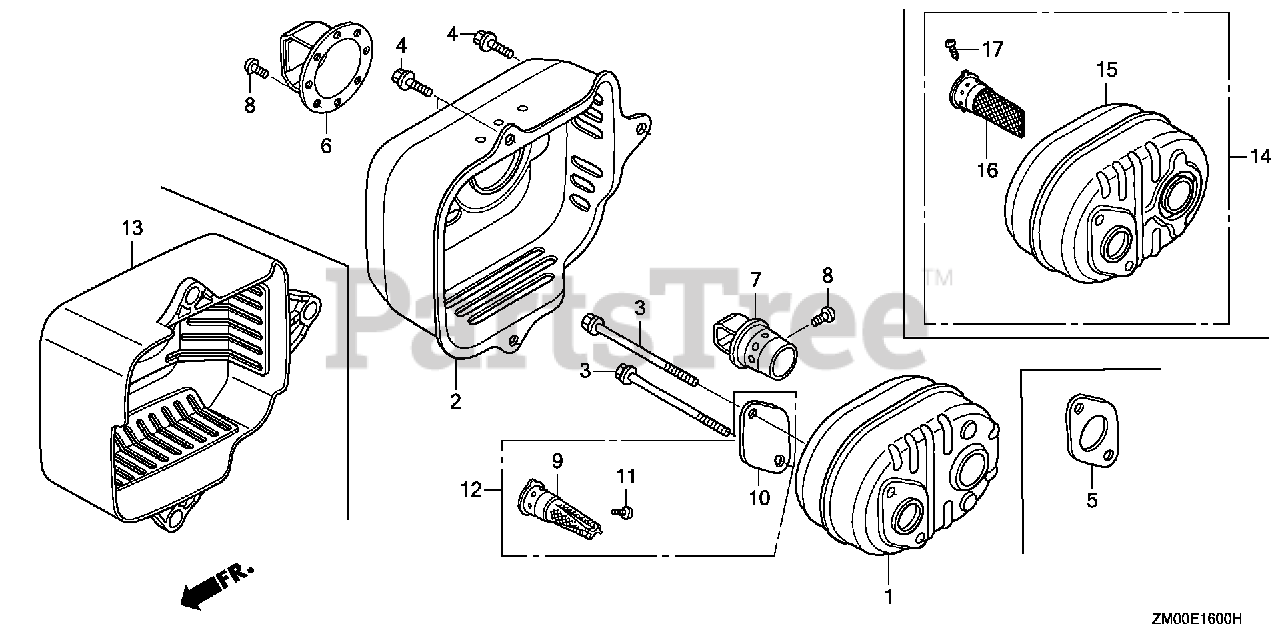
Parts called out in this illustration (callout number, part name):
2	PROTECTOR, MUFFLER
3	BOLT, FLANGE (6X79) (CT200)
4	BOLT, FLANGE (6X12) (CT200)
5	GASKET, MUFFLER
14	MUFFLER ASSY. (ARRESTER)
15	MUFFLER
16	ARRESTER, SPARK
17	SCREW, TAPPING (4X6) (TO INSTALL OPTIONAL SPARK ARRESTER)
